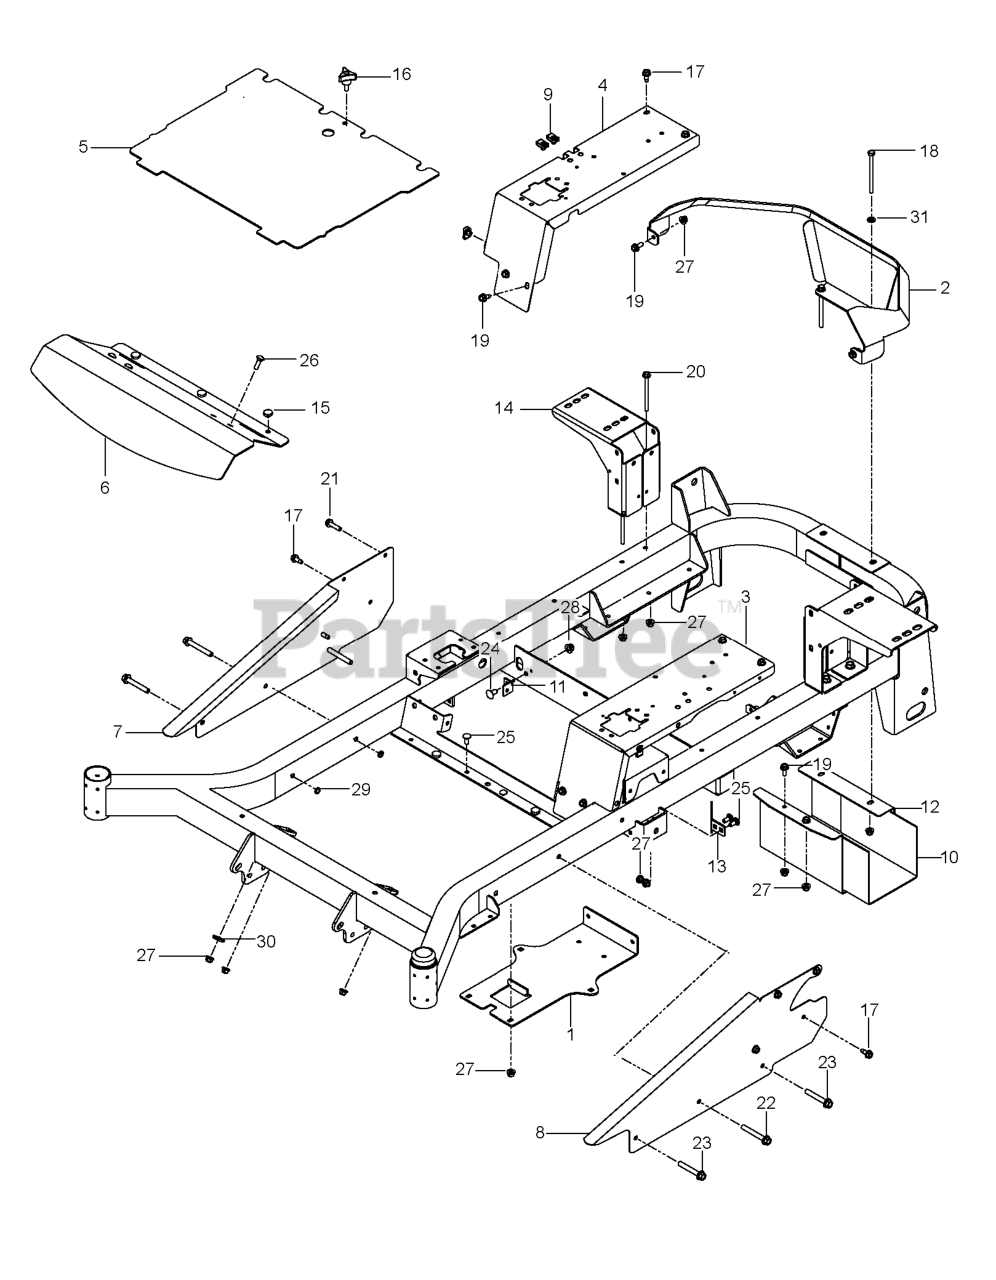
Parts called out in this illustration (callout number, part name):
1	PLATE, BATTERY, BLACK
2	GUARD, REAR MZ, GRAY
3	PANEL.FILLER.LT.ORANGE
4	PANEL.FILLER.RT.ORANGE
5	PLATE, FLOOR W/DECALS
6	PLATE, FOOTREST
7	SIDE.RT.ORANGE
8	SIDE.LT.ORANGE
9	U-CLIP 5/16-18 NUT RETAINER
10	HEAT SHIELD
11	BRACKET.DAMPENER.BLACK
12	SHIELD.MUFFLER.BLACK
13	STOP, DECK, EZ+
14	MOUNT, TANK, ZT BLK
15	GROMMET, BUMPER
16	KNOB W/STUD
17	BOLT 5/16-18 X 3/4
18	HCS 5/16C X 4
19	HHFS 5/16-18 X 3/4
20	HHFS 5/16-18 X 3 3/4
21	HHFS 5/16-18 X 1.25 TPBLT GD 5
22	HHFS 3/8-16 X 2 3/4
23	HHFS 3/8-16 X 2.5 GR 5 ZD
24	RHSNB 3/8-16 X 3/4 GR 5 BLK ZN
25	BOLT 5/16C X 3/4" CARRIAGE
26	RHSNB 5/16C X 1
27	5/16-18 NYLOC FLANGE NUT
28	NUT 3/8-16 HEX FLG NYLOC ZD
29	NUT HEX 3/8-16 NYLON, THIN
30	WASHER 1/2" FLAT
31	FLAT WASHER 5/16 SAE
